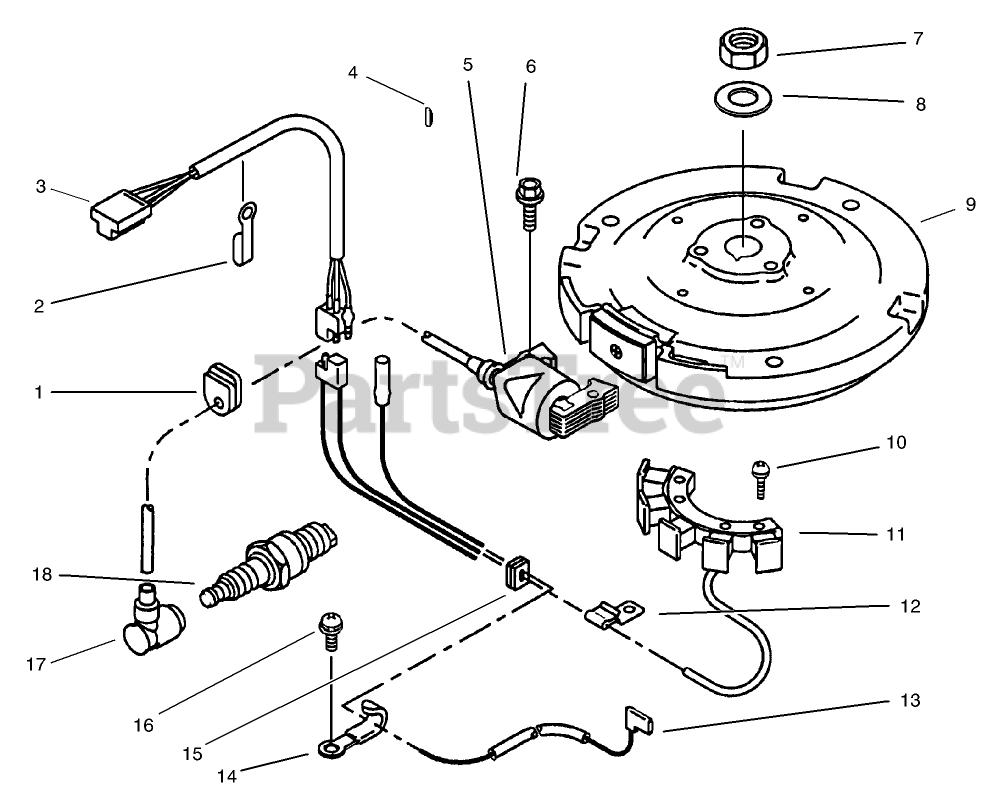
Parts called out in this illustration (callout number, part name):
1	Grommet
2	Clamp
3	Harness
4	Key
5	Coil-Ignition
6	Bolt-Flange
7	Nut
8	Washer
9	Flywheel
10	Screw
11	Coil-Charging
12	Clamp
13	Wire-Lead
14	Clamp
15	Grommet
16	Screw
17	Cap-Spark
18	Spark Plug-Rcj8
